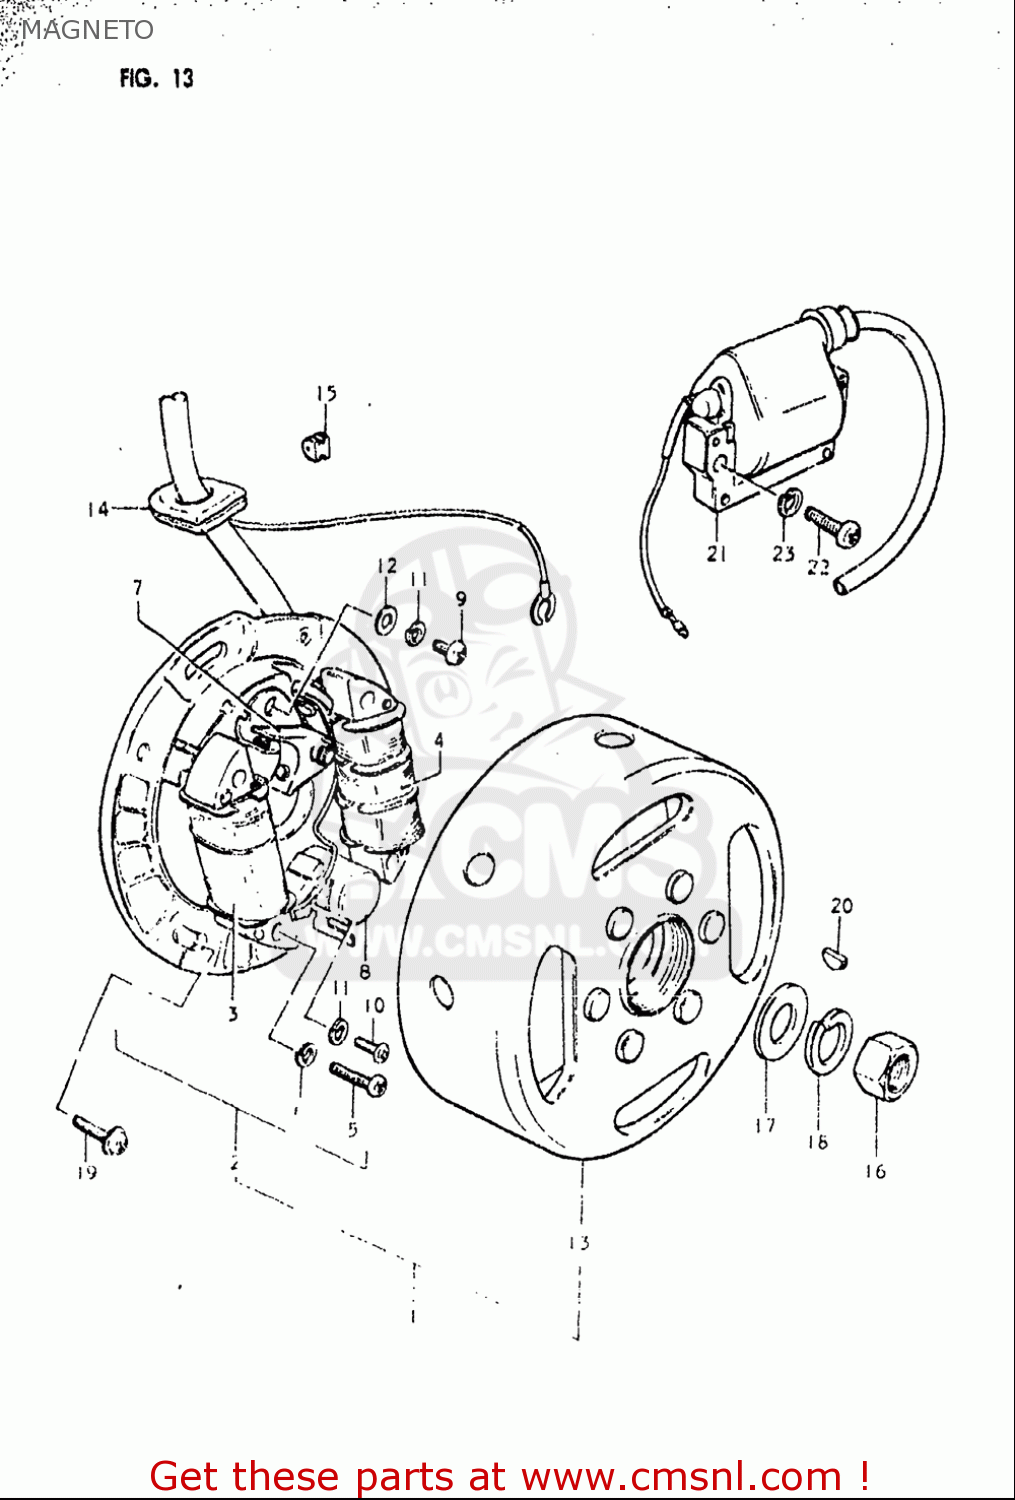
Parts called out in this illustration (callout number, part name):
5	SCREW
6	WASHER,LOCK
7	POINT ASSY,CONTACT
8	CONDENSER
9	SCREW(4X10)
10	SCREW
11	WASHER,LOCK
12	WASHER
14	GROMMET
16	NUT
17	WASHER
18	WASHER,LOCK
19	SCREW(5X14)
20	KEY
21	COIL ASSEMBLY,IGNITION
22	SCREW
23	WASHER,LOCK
